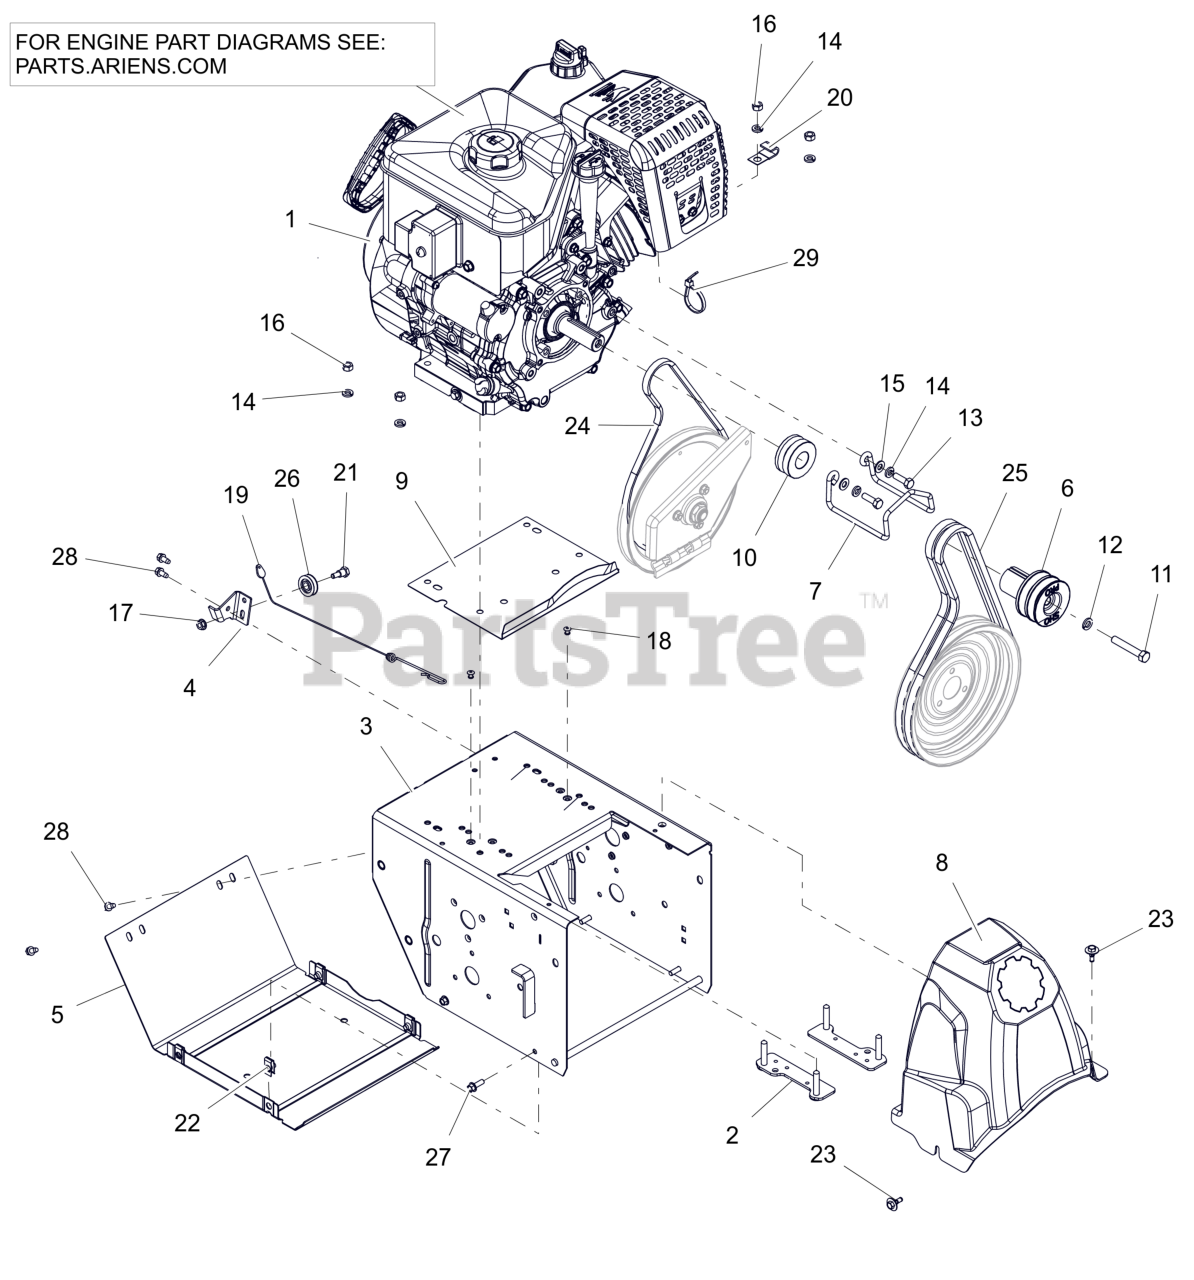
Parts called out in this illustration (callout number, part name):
1	ENGINE, AX369 GEN3 120V/60W
2	STRAP, BOLT-LARGE
3	FRAME, MAIN - 14GA DELUXE (ORANGE)
4	BRKT, CABLE PULLEY
5	COVER, BOTTOM
6	SHEAVE,ATTACHMENT-SHO 2 GRV
7	FINGER, BELT
8	COVER- BELT-LARGE
9	BAFFLE, WATER - LARGE BLOCK (ORANGE)
10	SHEAVE, TRACTION (KEYLESS)
11	BLT, HEX .38-24X2.25 G5 ZCC
12	WSHR,LK-REG .375X.094 ZCC
13	BLT, HEX 0.3125-24X1 G5 ZCC
14	WSHR, LK-HVY .312X.097 ZCC
15	WSHR,FLT .344X.688X.065 ZCC
16	NUT, HEX .312-18 ZCC
17	NUT-LK-TOP-FLG .250-20 GF ZCC
18	RVT, POP .1875 ZCC
19	CABLE, LOWER TRACTION,SS & PRO
20	J-CLAMP
21	BOLT, SHLDR -.375 X .375 X .25-20
22	NUT-RTNR .25-20X.56
23	SCR-TAP .25-20X.5 CAPTIVE
24	V-BELT, 3L-WRAPPED
25	V-BELT, HA-RAW EDGE (SET)
26	PULLEY, CABLE
27	BLT, HWH .25-20X.75 G5 ZCC
28	SCR-TAP .25-20X.50 HWH ZCC
29	CABLE TIE LG 5-1/2
